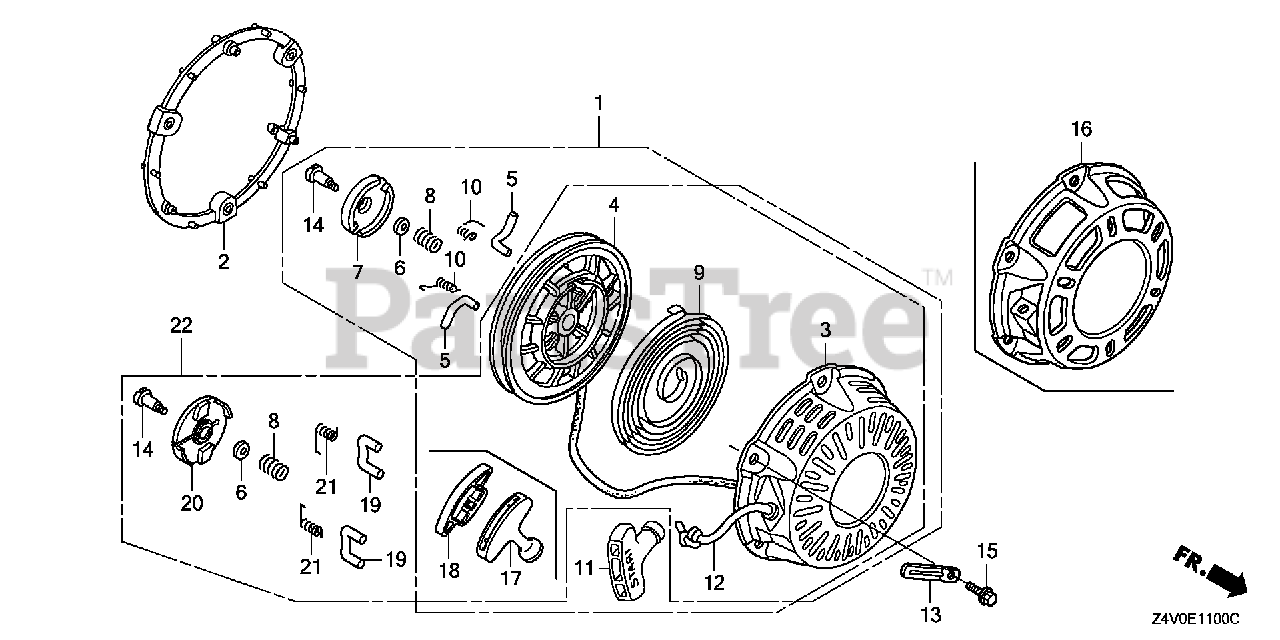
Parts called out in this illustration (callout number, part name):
1	STARTER ASSY., RECOIL *NH1* (BLACK)
1	STARTER ASSY., RECOIL *R280* (POWER RED)
2	SPACER, RECOIL STARTER MOUNTING *NH1* (BLACK)
2	SPACER, RECOIL STARTER MOUNTING *R280R* (POWER RED)
3	CASE, RECOIL STARTER *R280* (POWER RED)
3	CASE, RECOIL STARTER *NH1* (BLACK)
4	REEL, RECOIL STARTER (BLACK)
5	RATCHET, STARTER
6	PLATE, FRICTION
7	GUIDE, RATCHET
8	SPRING, FRICTION
9	SPRING, RECOIL STARTER
10	SPRING, RETURN
11	GRIP, STARTER
11	KNOB, RECOIL SRARTER
12	ROPE, RECOIL STARTER
13	CLIP, SUB-WIRE
14	SCREW, SETTING
15	BOLT, FLANGE (6X18)
